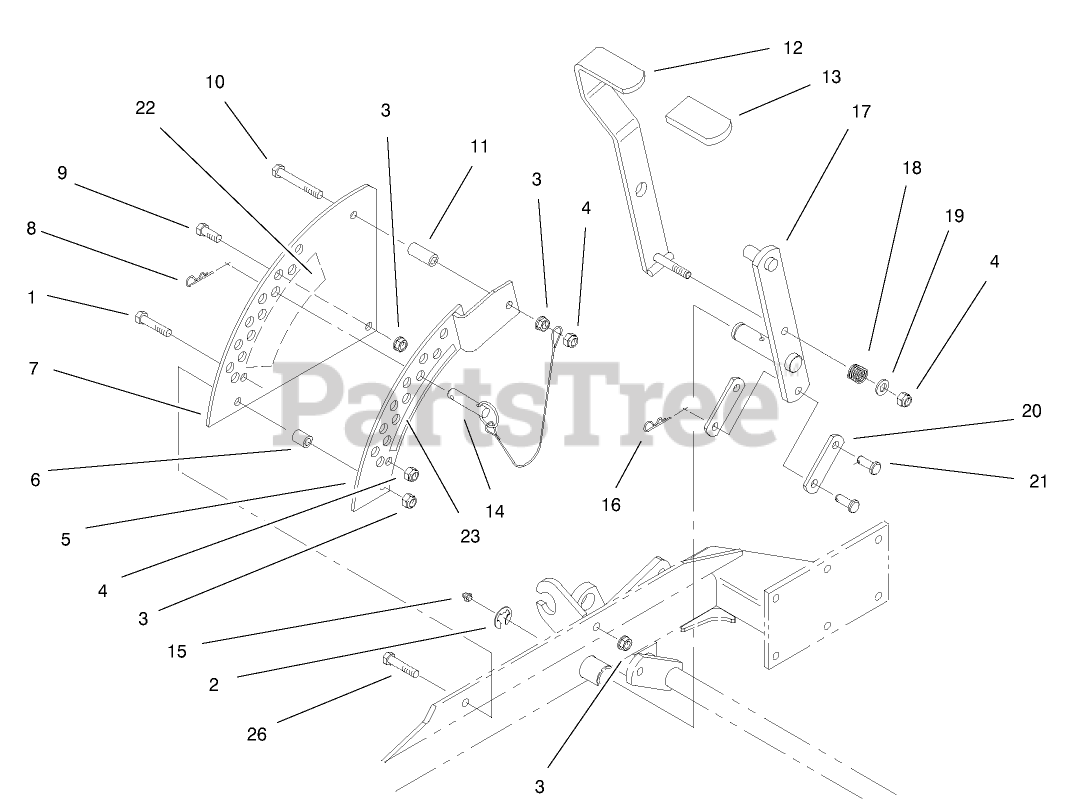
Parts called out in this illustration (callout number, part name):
1	SCREW-HH
2	RING-RETAINING, EXT
3	NUT-HHF, WHIZ
4	NUT-LOCK, NI
5	PLATE-LIFT, DECK
6	BUSHING-LEVER, LIFT
7	PLATE-LIFT, DECK
8	PIN-COTTER
9	SCREW-HH
10	SCREW-HH
11	BUSHING-LEVER, LIFT
12	HANDLE-LIFT
13	GRIP-LEVER, LIFT
14	PIN-HITCH (W/LANYARD)
15	FITTING-GREASE
16	PIN-COTTER
17	ARM-LIFT
18	SPRING-COMPRESSION
19	WASHER-FLAT
20	ARM-LIFT, DECK
21	PIN-CLEVIS
22	DECAL-DECK HEIGHT, OUTER
23	DECAL-DECK HEIGHT, INNER
26	SCREW-HH
